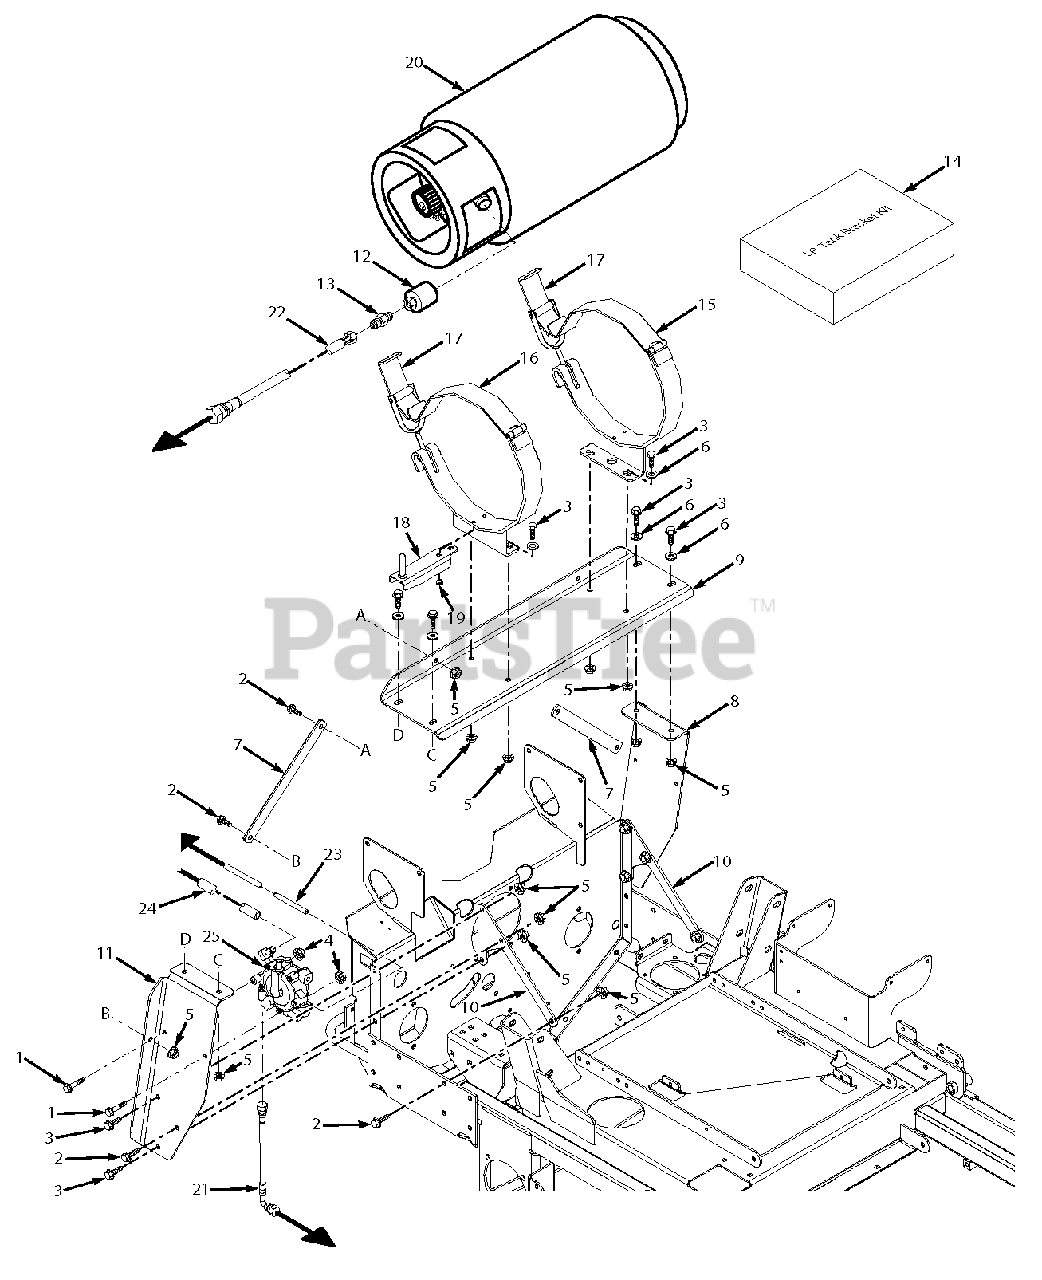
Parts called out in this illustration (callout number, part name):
1	Bolt, Heax Head 5/16-18 x 1-3/4"
2	Bolt, Head Head 3/8-16 x 3/4"
3	Bolt, Hex Head 3/8-16 x 1"
4	Nut, Serrated Flange 5/16-18
5	Nut, Serrated Flange 3/8-16
6	Flatwasher, 3/8-.391 x .938 x .105
7	Brace
8	Mounting Bracket, Tank Support LH
9	Support, LP Tank
10	Brace, LP Tank Mounting Bracket
11	Mounting Bracket, Tank Support RH
12	LP Quick Coupler
13	Adapter Fitting, 9/16-18 SAE x 1/4" Pipe
14	Mounting Bracket Kit
15	Mounting Bracket, LP Tank Front
16	Mounting Bracket, LP Tank Rear
17	Handle, LP Tank Mounting Bracket
18	Bracket, LP Tank Locator
19	Bolt, Hex Head 1/4-20 x 3/8" Locking
20	LP Tank
21	LP Fuel Line, 10"
22	LP Fuel Line, 32"
23	Hose
24	Hose
25	LP Regulator
